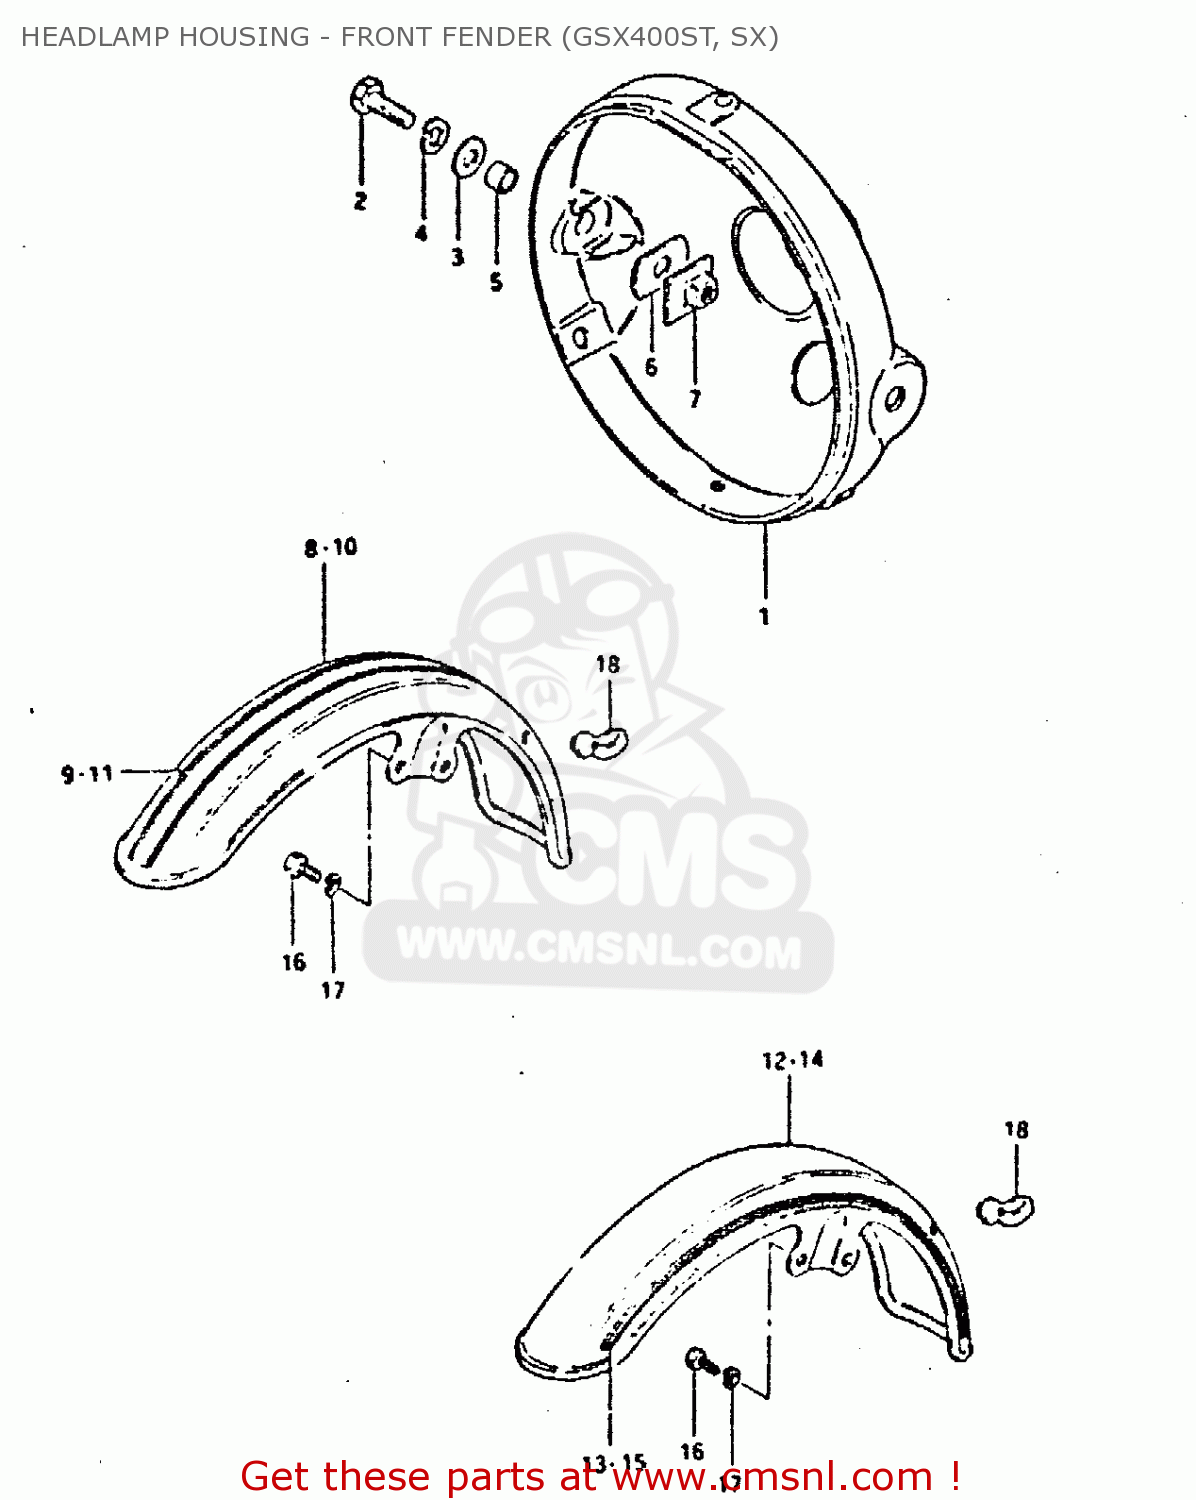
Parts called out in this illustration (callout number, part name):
1	HOUSING,HEADLAMP(BLACK)
2	BOLT
3	WASHER
4	LOCK WASHER
5	SPACER (8.8X12X7)
6	CUSHION
7	PLATE,HEADLAMP HOUSING
8	FENDER,FRONT
9	TAPE
10	FENDER,FRONT
11	TAPE
12	FENDER,FRONT
13	TAPE
14	FENDER, FRONT
15	TAPE
16	BOLT
17	LOCK WASHER
18	GUIDE,CABLE
